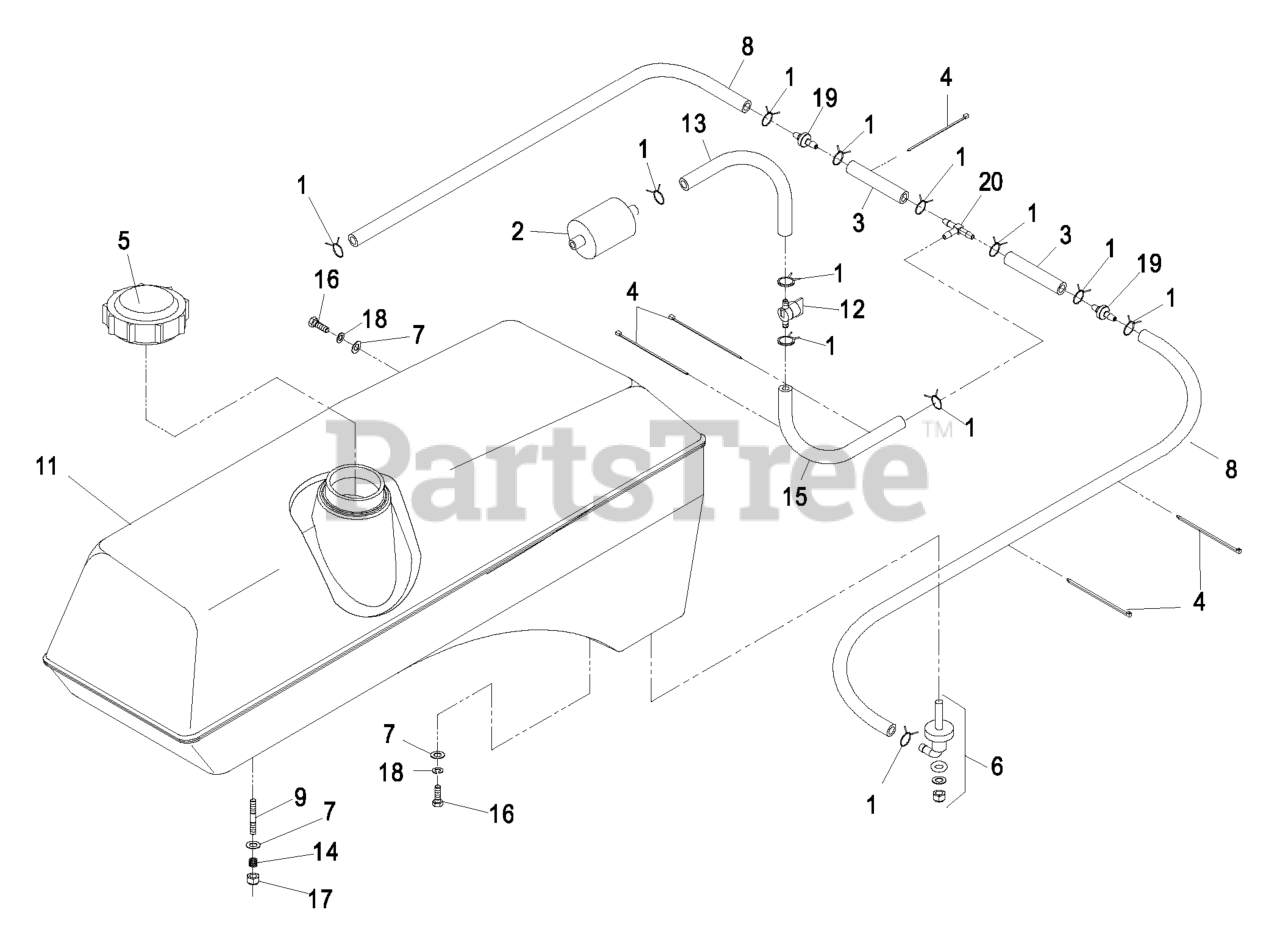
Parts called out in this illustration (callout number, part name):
2	Part No. 2405010 Fuel Filter
3	Hose, Fuel Line 2 1/2"
4	TIE-PLASTIC
5	CAP-FUEL, GAS
6	FITTING-FUEL, BULKHEAD
7	WASHER-PLAIN
8	HOSE-FUEL
9	STUD
12	VALVE-FUEL
13	HOSE-FUEL
14	SPRING-TANK, FUEL
15	HOSE-FUEL
16	SCREW-HH
17	NUT-LOCK, NI
18	WASHER-LOCK
19	VALVE-CHECK, FUEL
20	FITTING-TEE, BARBED
